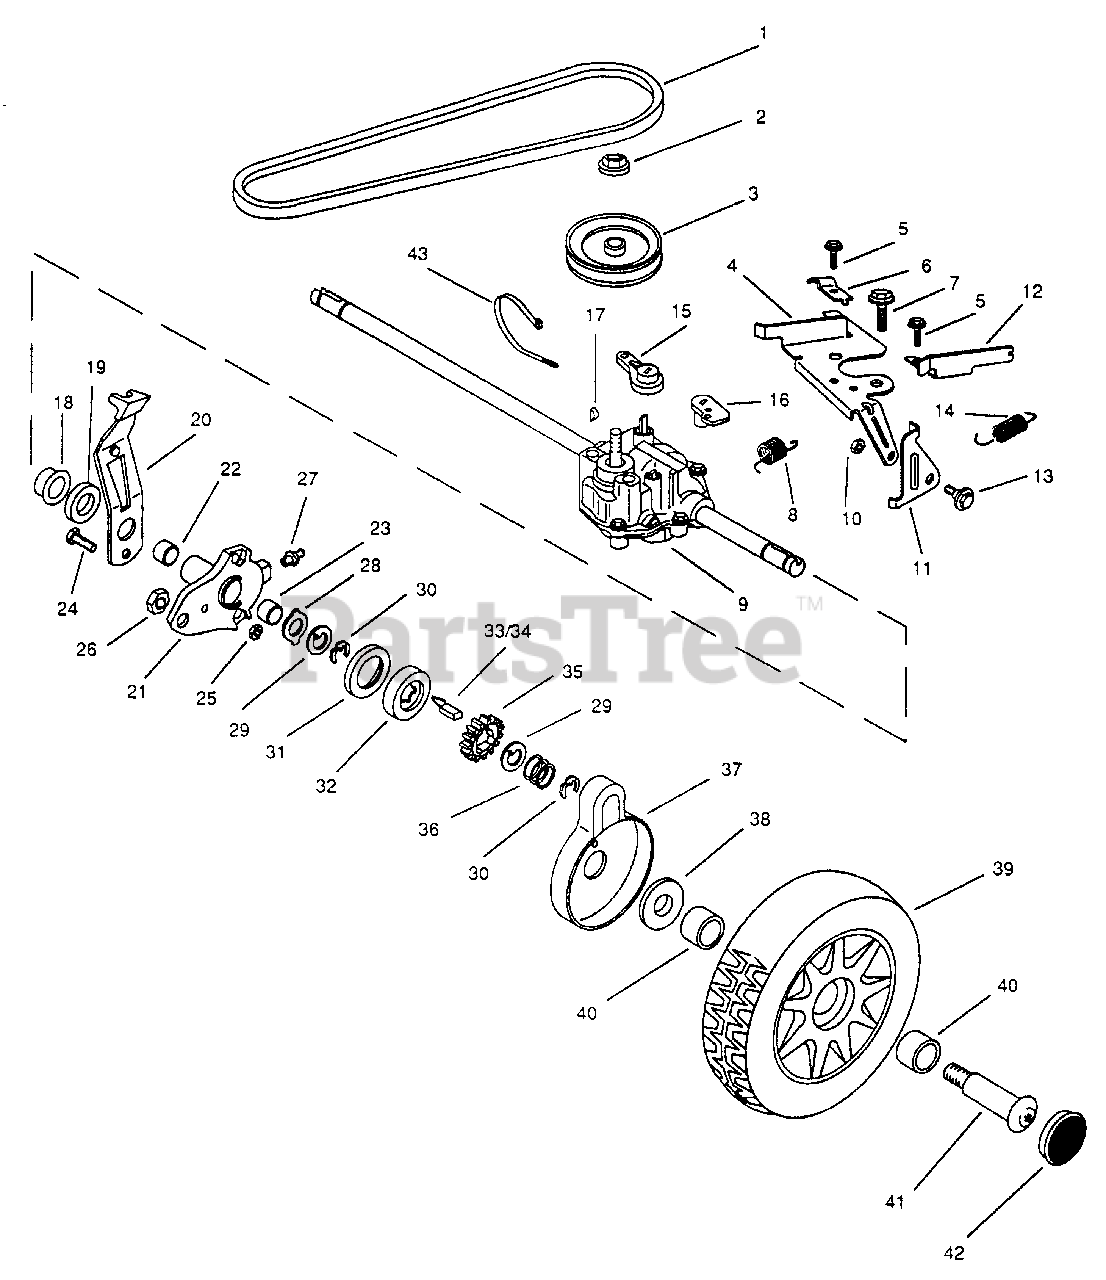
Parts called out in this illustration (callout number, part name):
1	V-Belt
2	Nut
3	Transmission Pulley
4	Actuator Plate
5	Screw
6	Clamp
7	Screw-Plate to Transmission
8	Spring
9	Transmission
10	Nut
11	Arm-Transmission Engagement
12	Guide-Belt
13	Shoulder Bolt
14	Spring-Extension
15	Arm-Shift
16	Arm-Clutch
17	Key
18	Isolator Ring
19	Spacer
20	Knob & Spring Assembly
21	Pivot Arm Assembly (Inc 22-23)
22	Bushing
23	Bushing
24	Screw
25	Locknut
26	Nut
27	Grease Fitting
28	Washer-InnerThrust
29	Washer-Keyed
30	Ring-Retaining
31	Ring-Friction
32	Washer-Clutch
34	Key, Rocking-L.H.
35	Gear-Pinion 15T
36	Spring-Compression
37	Cover-Wheel
38	Washer-Stepped
39	Wheel Assembly (Inc. 40)
40	Bushing
41	Wheel Bolt
42	Cap-Hub
43	Tie Strap
